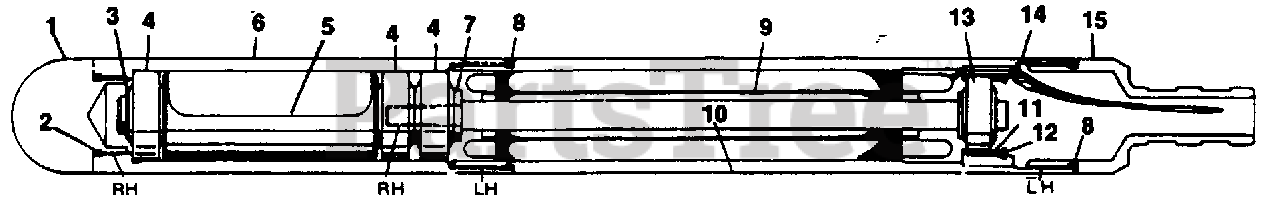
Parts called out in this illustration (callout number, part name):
1	NOSE-Steel
3	RING-Snap
5	ECCENTRIC
6	BARREL- Eccentric
10	MOTOR BARREL & STATOR
12	RING- Snap
15	CONNECTOR- Hose
